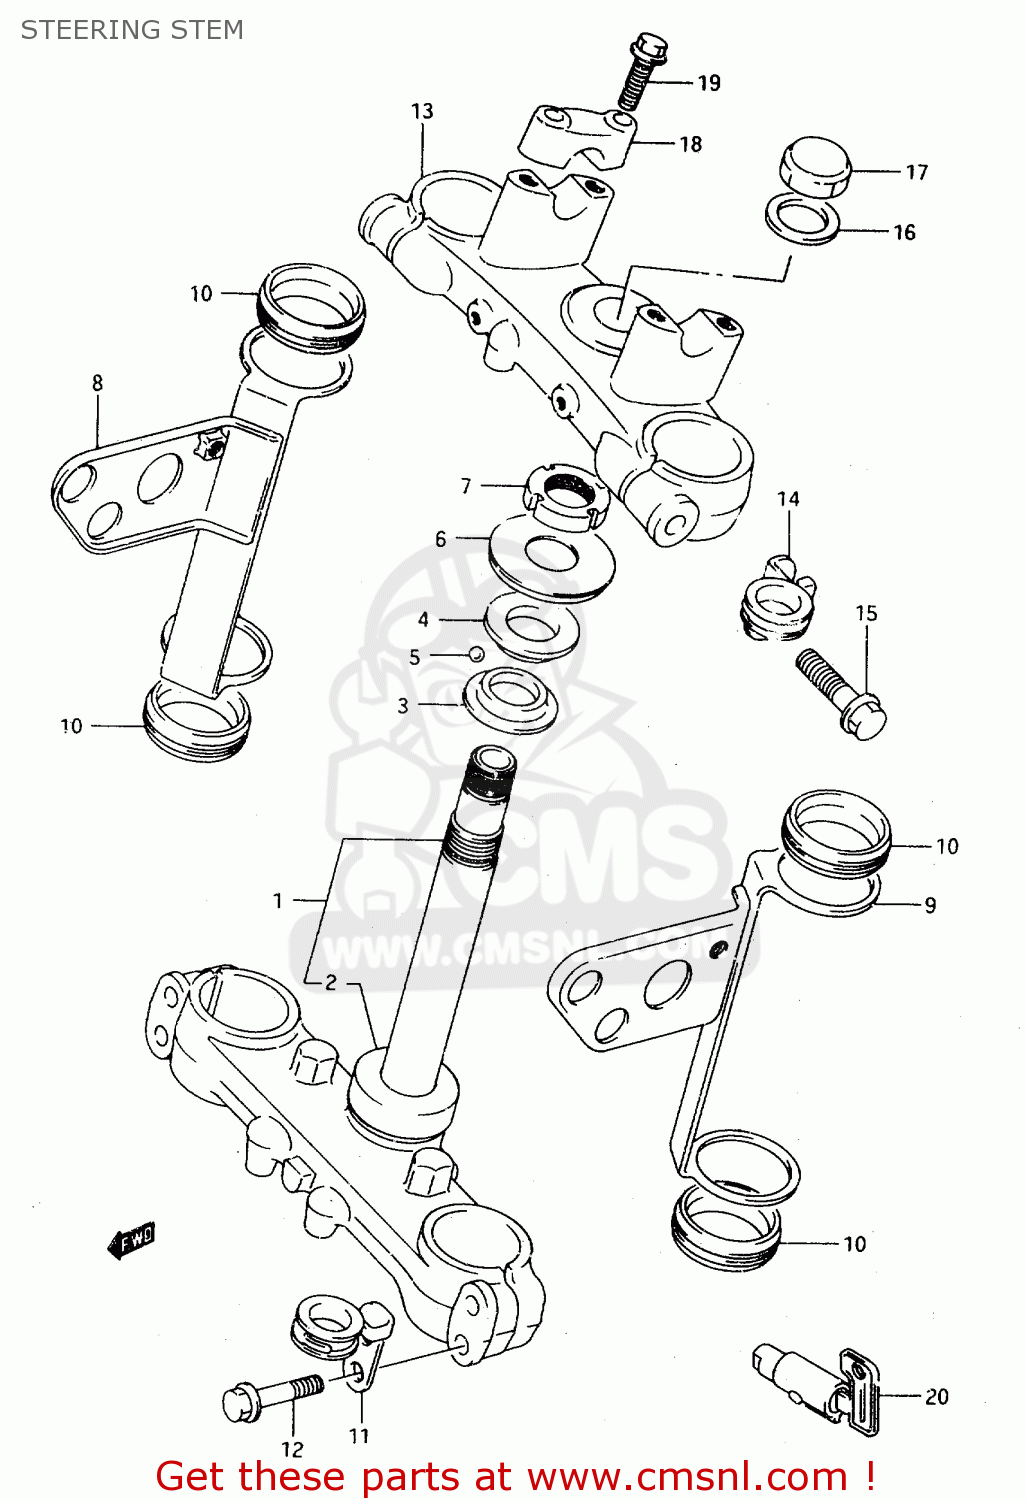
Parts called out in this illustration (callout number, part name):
1	STEM,STEERING
2	BEARING(30X55X17)
3	RACE,STEERING INNER (SUJ)
4	LACE,STEERING OUTER UPR
5	BALL
6	SEAL,STEERING UPR DUST
7	NUT,STEERING STEM
8	BRACKET, HEADLAMP RH
9	BRACKET,HEADLAMP HOUSING,L
10	DAMPER,HEADLAMP HSG BRACKET
11	GUIDE,CABLE LWR,L
12	BOLT 8X40
13	HEAD,STEERING STEM
14	GUIDE,CABLE UPR,L
15	BOLT
16	WASHER
17	NUT,CAP
18	HOLDER,HANDLE UPR
19	BOLT
20	LOCK ASSEMBLY,STEERING (NEI
